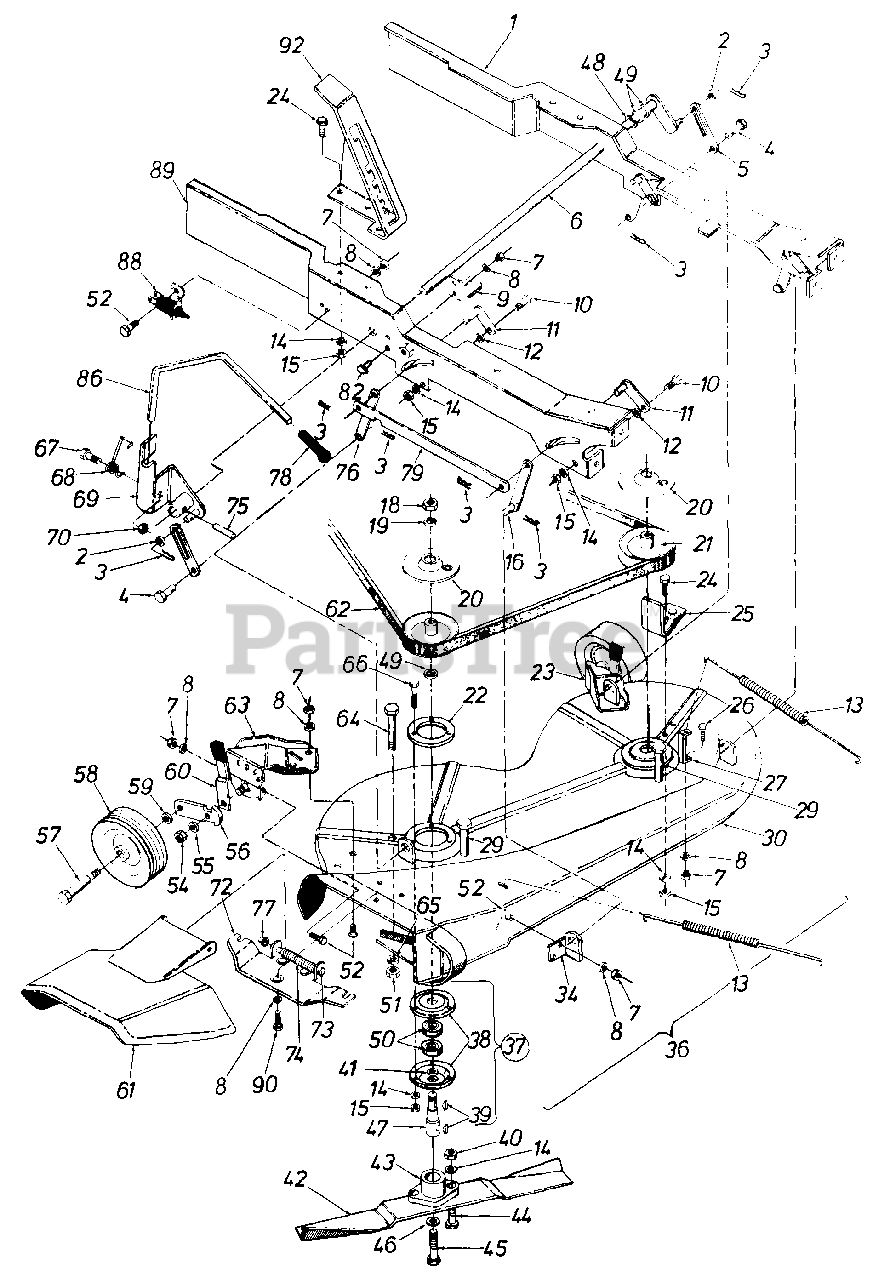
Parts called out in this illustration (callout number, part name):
1	Side Rail Ass'y. - L.H.
2	Flat Washer .531 I.D. x .930 O.D. x .090
3	Internal Cotterpin for .500"
4	Lift Brake Pin (Special)
5	Slotted Link
6	Lift Shaft Ass'y.
7	Hex Nut 1/4-20 Thd.
8	Spring Lock Washer 1/4" Scr.
9	Blade Brake Ass'y.
10	Shld. Scr. .437" Dia. x .180
11	Pivot Link Ass'y.
12	Flat Washer .344 I.D. x .62" O.D.
13	Deck Extension Spring
14	Spring Lock Washer 5/16"
15	Hex Nut 5/16-18 Thd.
16	Deck Link Ass'y.
18	Hex Jam L-Nut 5/8-11 Thd.
19	Spring Lock Washer 5/8" Scr.
20	Brake Disc Ass'y.
21	Deck Pulley
22	Reinforcement Plate
23	Wheel Bracket Ass'y. - L.H.
24	Hex Sems Scr. 5/16-18 x .75"
25	Belt Keeper Ass'y.
26	Hex Scr. 1/4-20 x .62" Thd.
27	Deck Spring Brkt.
29	Shld. Scr. .498" Dia. x 2.00"
30	Deck Ass'y.
34	Deck Bracket
36	34 Inch Deck Ass'y. - Comp.
37	Blade Spindle Ass'y. - Comp.
38	Bearing Cup
39	#6 Hi-Pro-Key 5/32 x 5/8"
40	Hex Nut 5/16-24 Thd.
41	Fl-Wash. .793 I.D. x 1.24 O.D.
42	17 Inch Blade
43	Blade Adapter Kit
44	Hex Scr. 5/16-24 x 1.00" Lg.
45	Hex Scr. 3/8-24 x 1.50" Lg.
46	Spring Lock Washer 3/8" Scr.
47	Blade Spindle
48	Wave Washer .62" I.D.
49	Flat Washer .635 I.D. x .930
50	Ball Bearing
51	Hex Nut 3/8-16 Thd.
52	Hex Scr. 1/4-20 x .50" Lg.
54	Hex Inserted Lock Nut 3/8-24
55	Belleville Washer .40" I.D. x 1.13 O.D. x .030
56	Wheel Pivot Bar
57	Shld. Scr. 5/8" Dia. x 1.75"
58	5" Wheel Ass'y.
59	Belleville Washer .400 I.D. x .88" O.D. x .060
60	Spring Lever Ass'y. w/knob
61	Chute Cover Ass'y. - Comp.
62	"V"-Belt 21/32 x 82" Lg.
63	Wheel Bracket Ass'y. - R.H.
64	Shld. Scr. .498" Dia. x 1.450" Lg.
65	Spring Lock Washer 3/8" Scr.
66	Hex Sems Scr. 5/16-18 x 1.00"
67	Hex Scr. 1/4-20 x 1.50" Lg.
68	Torsion Spring
69	Handle Bracket Ass'y.
70	Hex Center Lock Nut 1/4-20
72	Adapter Ass'y.
73	Hinge Pin
74	Torsion Spring
75	Spring Pin 5/16" Dia. x 1.38"
76	Deck Link
77	Push Nut 1/4" Rod
79	Connecting Rod
82	Carriage Bolt 1/4-20 x .62"
86	Lift Handle
88	Safety Switch
89	Side Rail Ass'y. - R.H.
90	Hex Scr. 1/4-28 x .62" Lg.
92	Index Bracket
